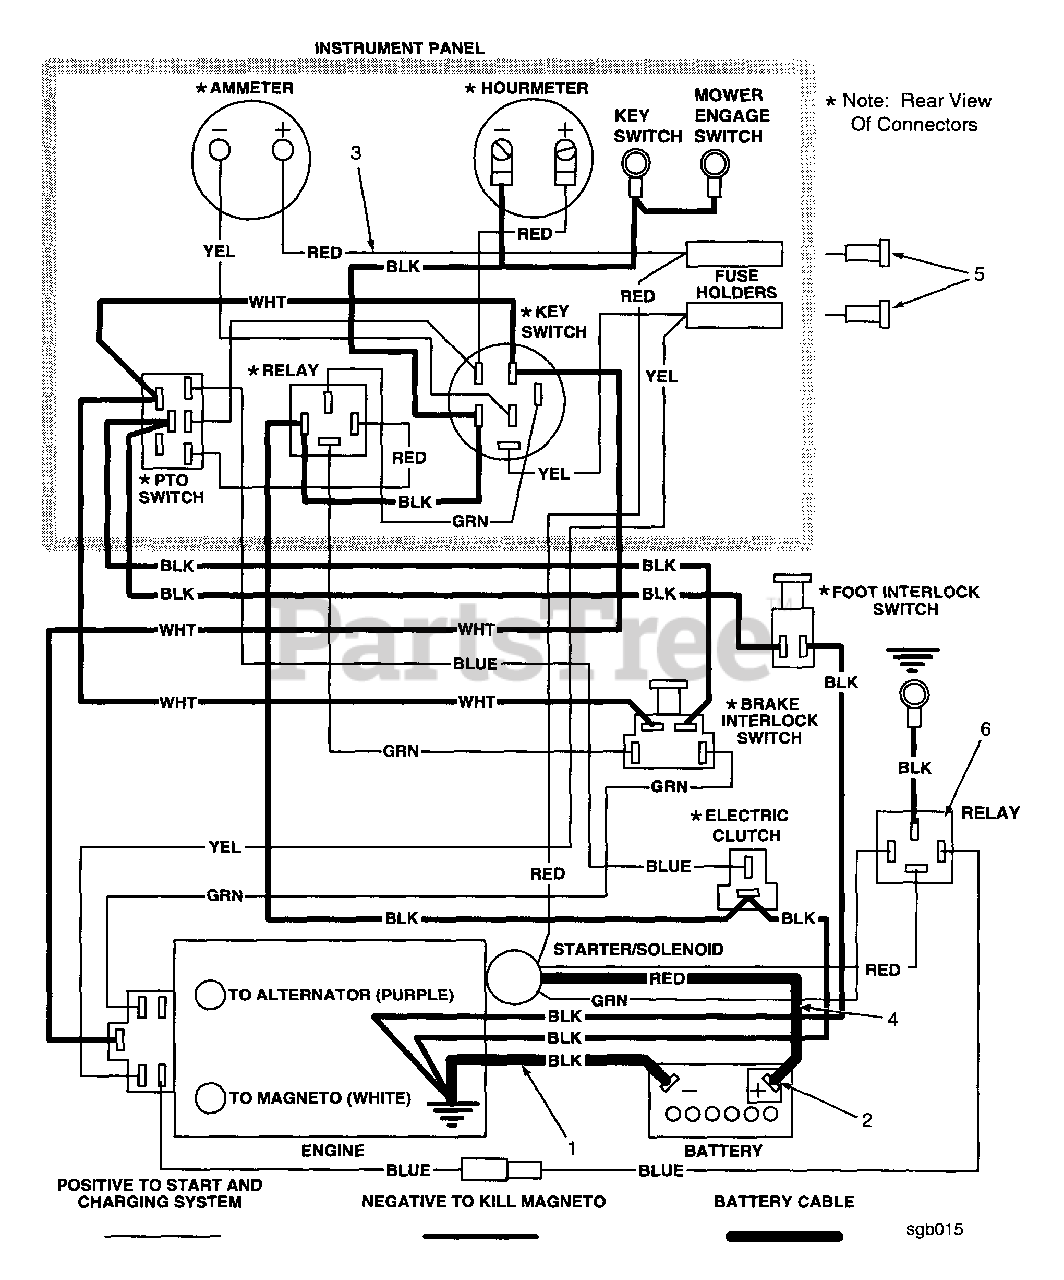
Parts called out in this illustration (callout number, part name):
1	Battery Cable, 36" Black
2	Rubber Boot
3	Wire Harness, STHM
4	Battery Cable, 25" Red
5	Fuse, 20 AMP Blade Automotive
6	Wire Harness With Relay
